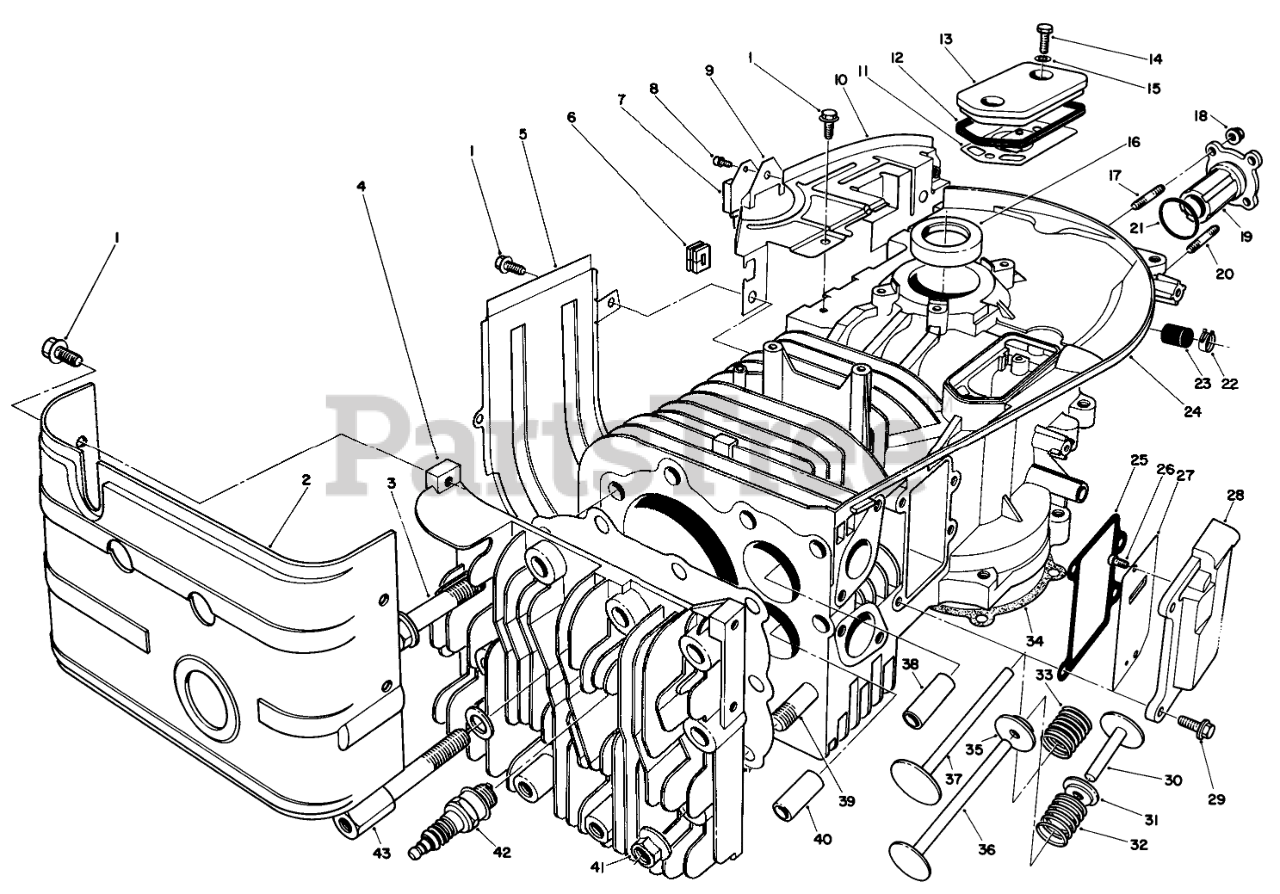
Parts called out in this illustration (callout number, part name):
1	BOLT-FLANGED (6X10)
3	Bolt
4	Head-Cylinder
6	Grommet
7	Igniter
8	Screw
10	Housing-Fan
14	Bolt
18	Nut
24	Crankcase Assembly
25	Gasket
28	Cover-Valve Chamber
29	Bolt-Flanged (6X16)
31	Retainer-Spring
32	Spring-Valve
33	Spring-Valve
34	Gasket
36	Valve-Exhaust
37	Valve-Intake
38	Guide-Valve Intake
40	Guide-Valve Exhaust
42	Spark Plug
